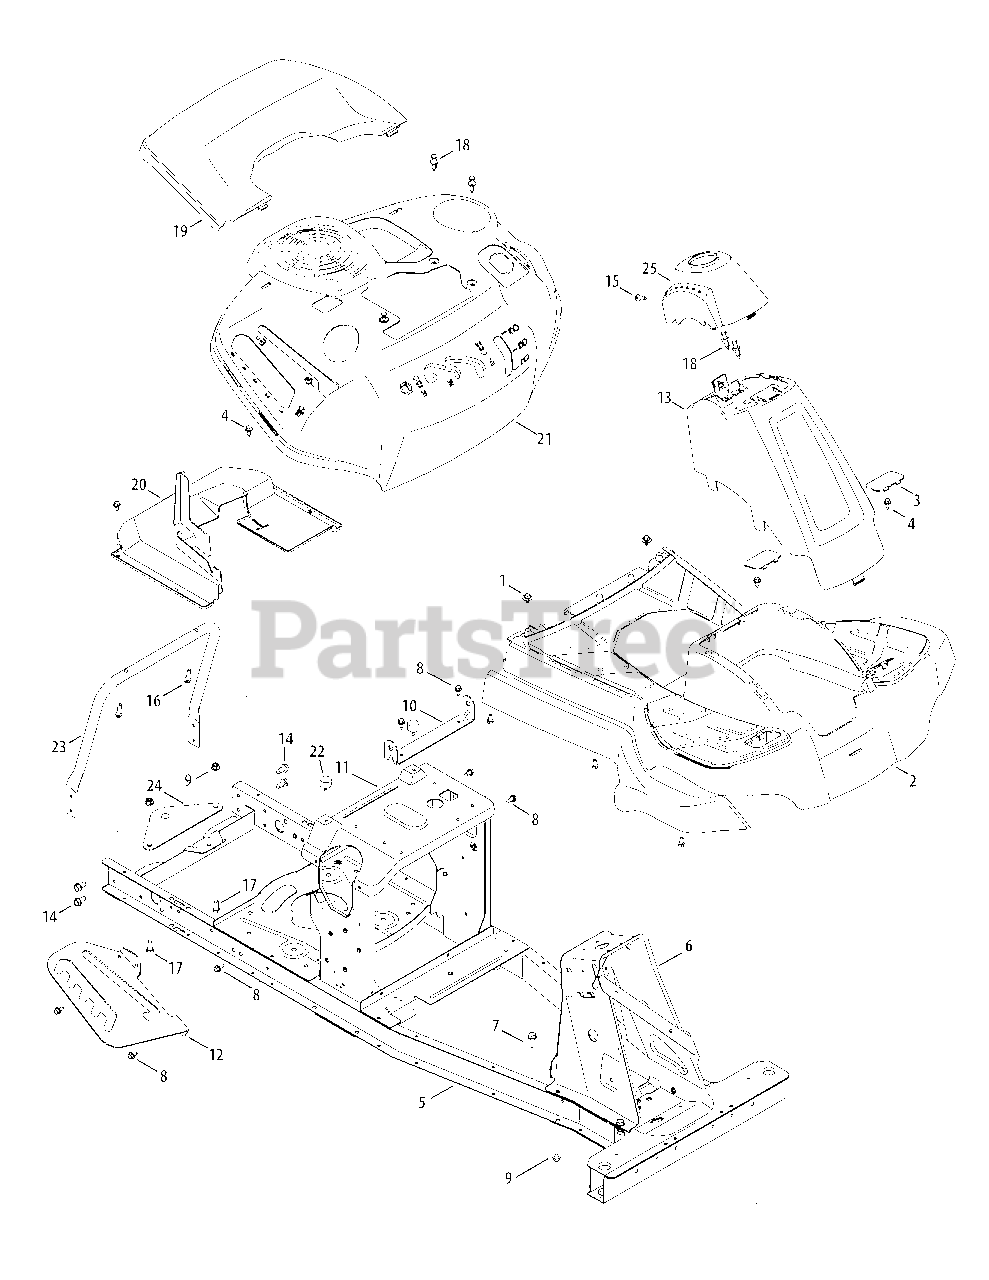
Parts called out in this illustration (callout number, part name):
1	Screw, 1/4-20 x .500
2	Running Board, NRMC
3	Running Board Plug
4	Shoulder Screw, .368 X.113: 1/4-20
5	Frame Assembly
6	Column Assembly
7	Hex Washer Screw, 5/16-18 x .75
8	Tap Screw, 1/4-20, .625
9	Hex Locknut, 5/16-18
10	Seat Pivot Bracket
11	Seat Pan
12	Deck Lift Index Bracket
13	Column Cover, Red
14	Tap Screw, 5/16-18, .750
15	Machine Screw, 1/4-20, 0.750
16	Hex Screw, 1/4-15, 1.000
17	Hex Head Screw, 5/16-18, .75
18	Rivet, .3125
19	Rear Cover, Red
20	Top Rear Drive Cover
21	Fender, (B&S Eng.)
22	Bumper, .62 Dia. x .50
23	Rear Cover Support Tube
24	Hitch Plate
25	Steering Column Cap, Red
